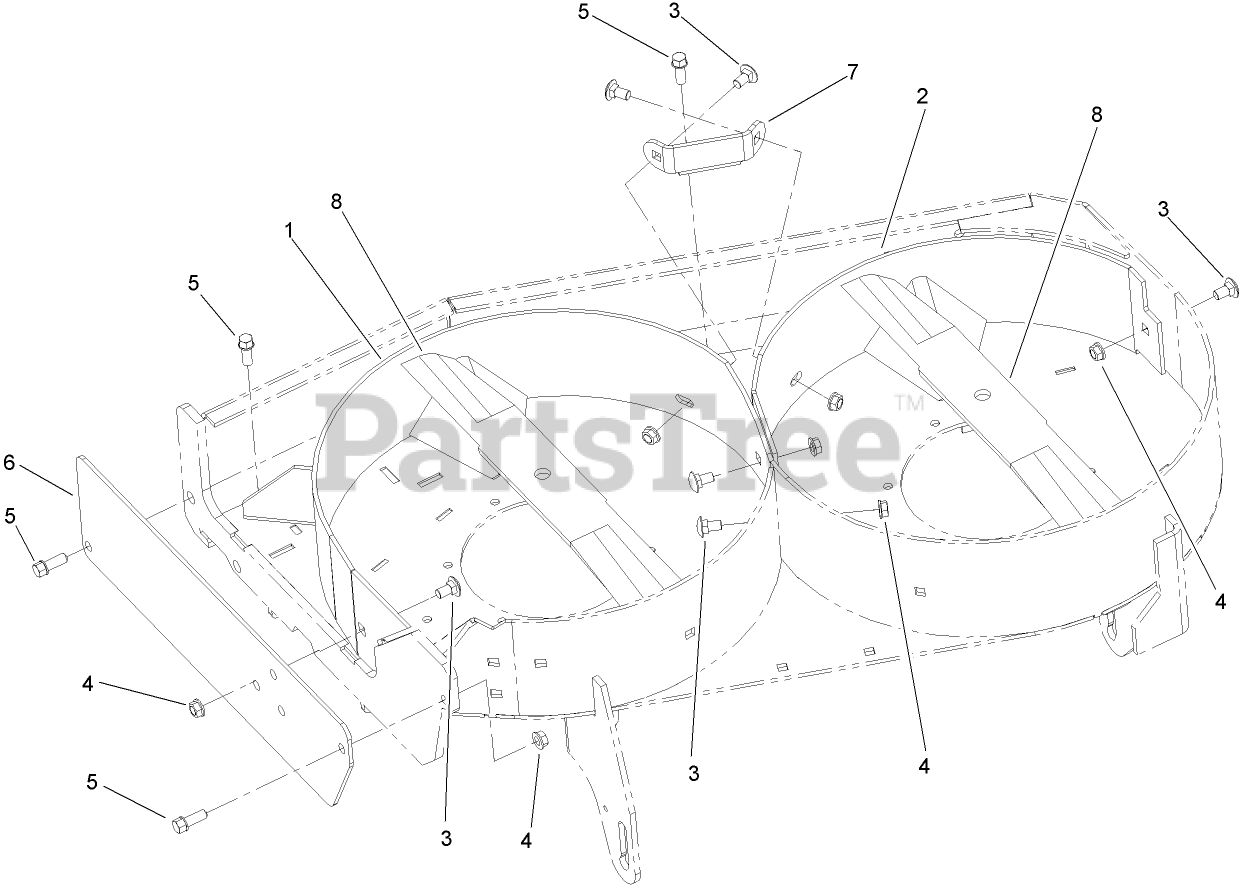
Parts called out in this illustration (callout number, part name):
1	BAFFLE-WELDED
2	BAFFLE-WELDED
3	SCREW-CARR
4	NUT-HHF, WHIZ
5	SCREW-HWH
6	PLATE-DISCHARGE
7	ANGLE-SUPPORT
8	BLADE-ROTARY, RECYCLING (17.50)
